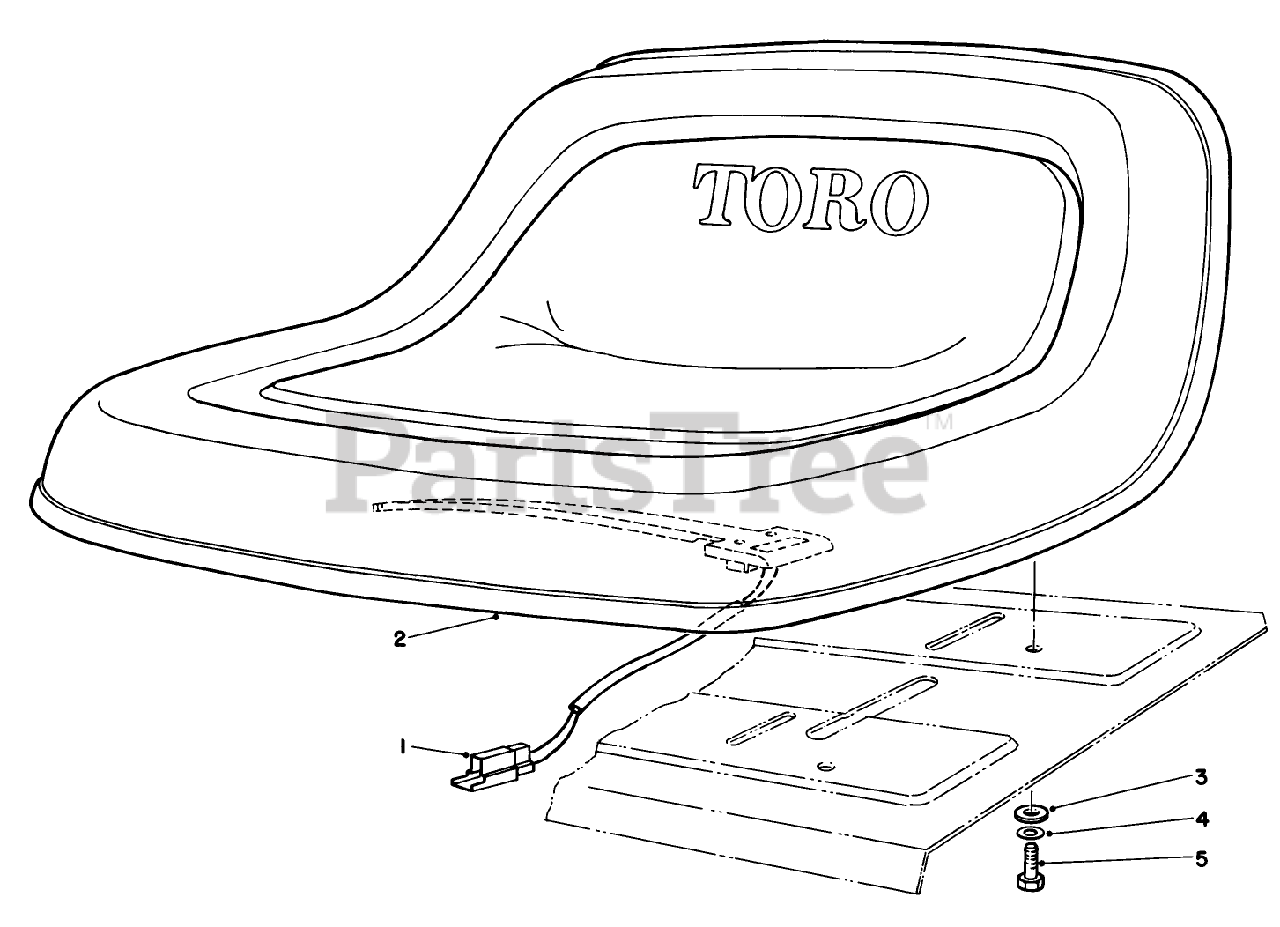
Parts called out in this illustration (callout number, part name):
1	SWITCH-SEAT
2	Seat
3	WASHER-PLAIN
4	WASHER-LOCK
5	SCREW-HH
